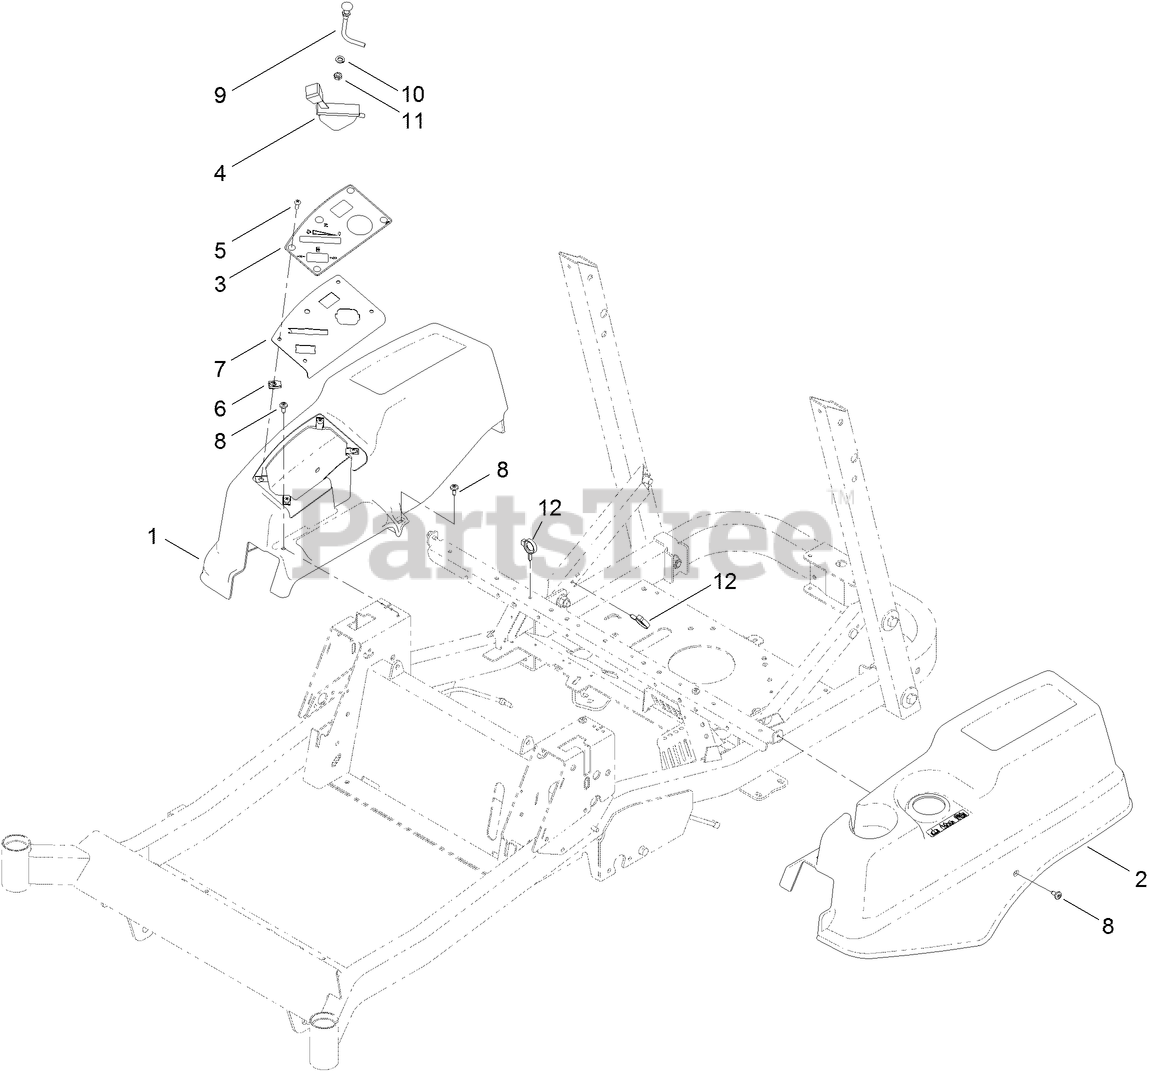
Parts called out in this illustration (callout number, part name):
1	POD-RH
2	POD-LH
3	DECAL-PANEL, CONTROL
5	SCREW-PRH
7	PANEL-CONTROL
9	CABLE-CHOKE
10	WASHER-LOCK
11	NUT-HJ
12	CLAMP-HOSE
